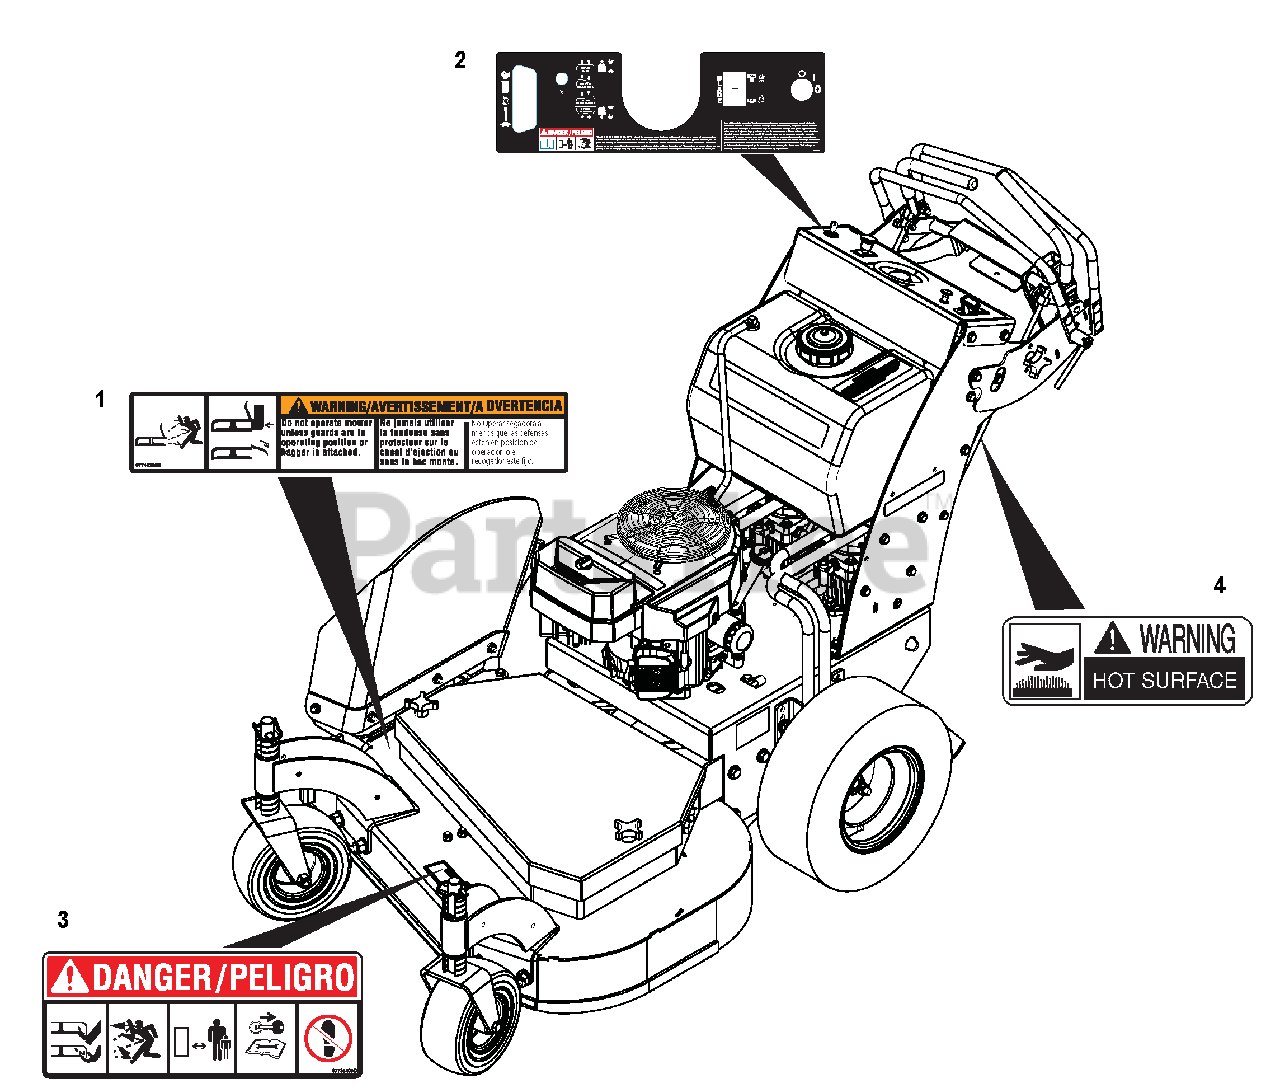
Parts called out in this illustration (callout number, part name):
1	DECAL, WARNING
2	DECAL, CONSOLE
3	DECAL, MOWER PAN DANGER
4	LABEL, WARNING (HOT SURFACES)
